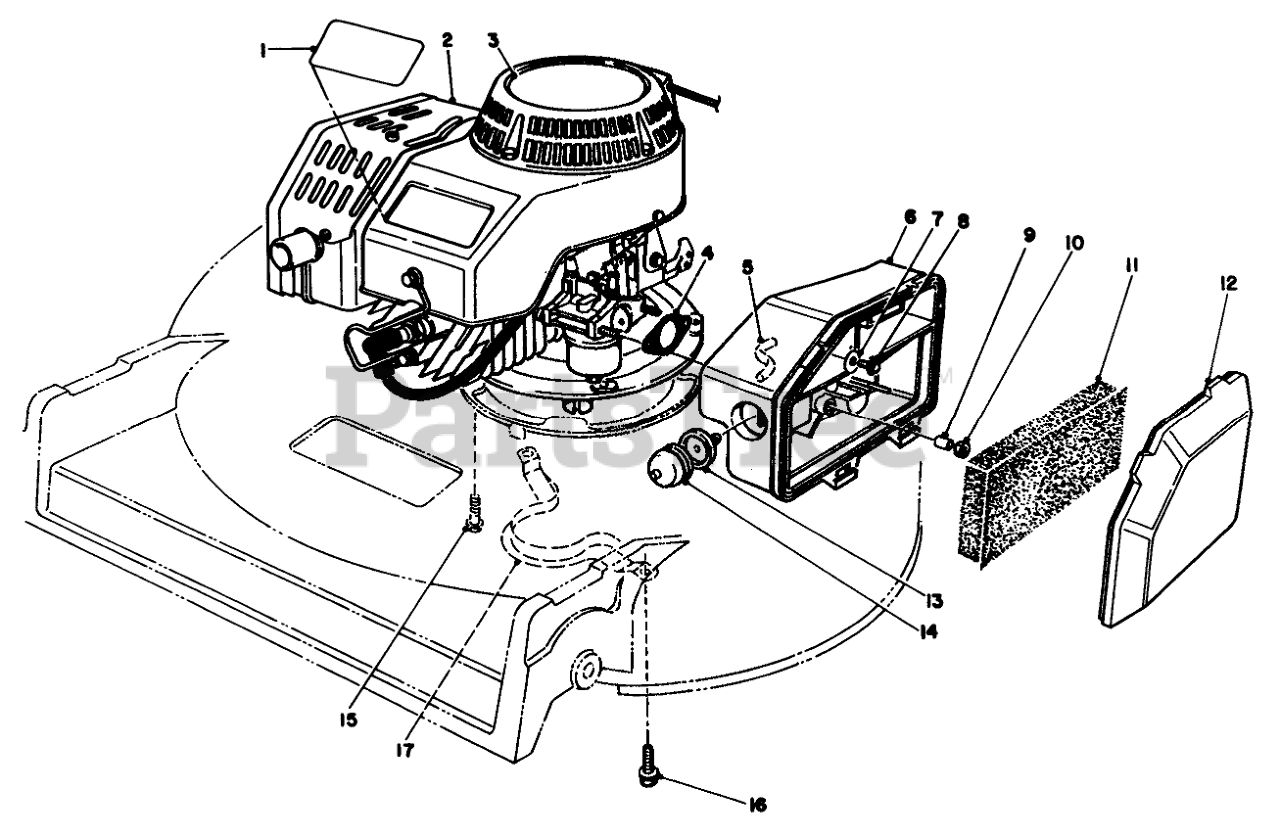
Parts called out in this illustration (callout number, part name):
1	DECAL - PROLINE
2	ENGINE ASM - BBC 2 CYCLE
3	DECAL-2 CYC RECOIL COMM
4	GASKET-AIR CLEANER
5	HOSE-PRIMER
6	BODY-AIR CLEANER
7	WASHER-FLAT
8	SCREW-HH
9	SPACER
11	ELEMENT-AIR CLEANER
12	COVER-AIR CLEANER
13	BODY-PRIMER
14	BULB-PRIMER
15	SCREW-HHF
16	SCREW-HWHTF
17	Guide-Belt
